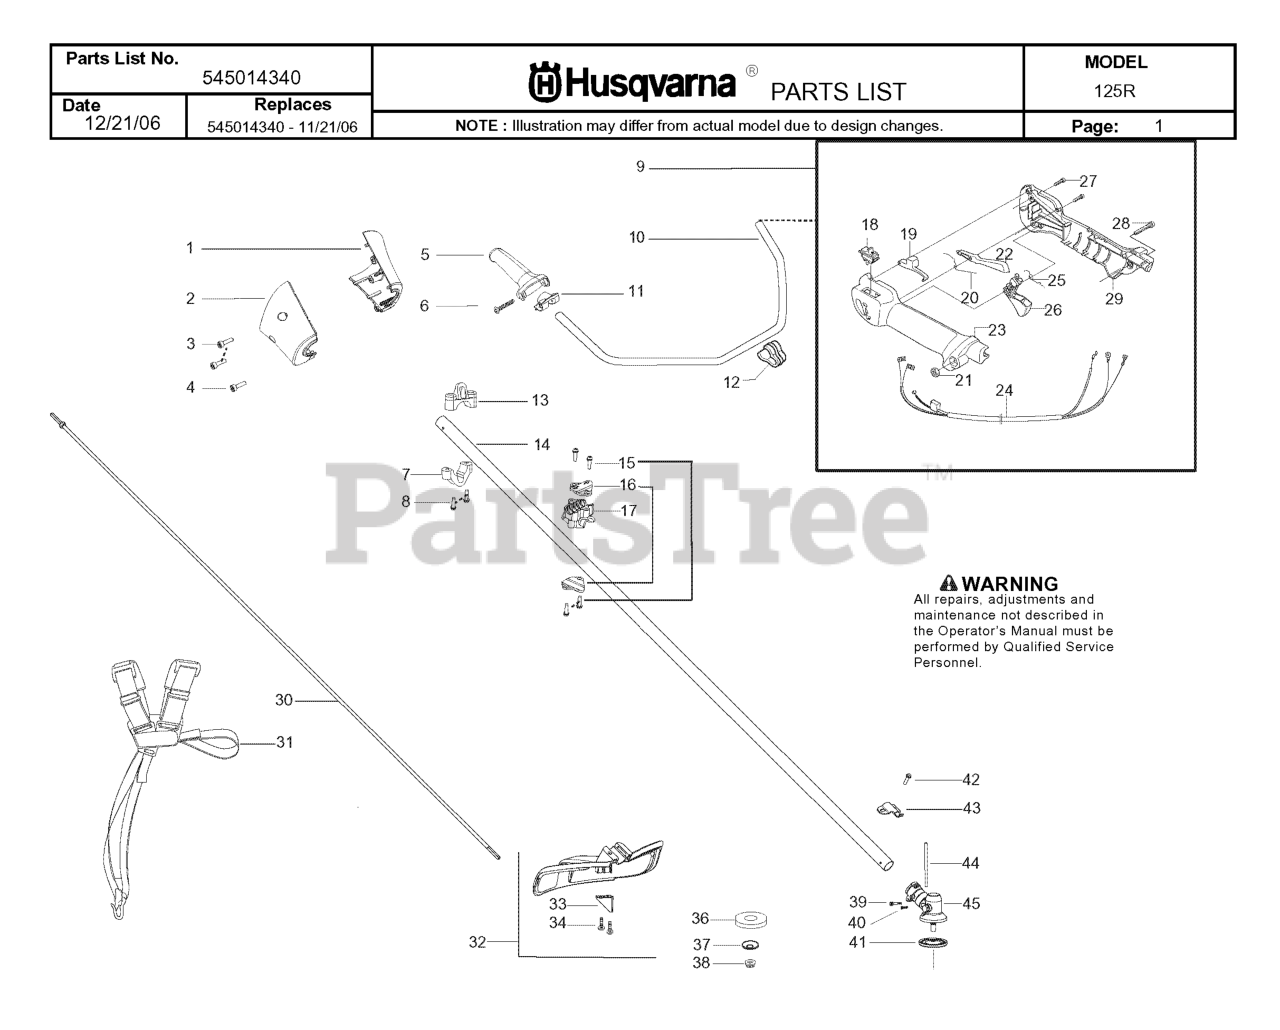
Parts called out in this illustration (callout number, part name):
1	NOSE CONE BH LEFT
2	NOSE CONE BH RIGHT
4	SCREW M4 X 1.75 PT 16MM
7	CLAMP HARNESS LOWER
9	ASSY THROTTLE HOUSING
13	CLAMP HARNESS UPPER
14	DRIVE SHAFT ASSY
16	CLAMP BRACKET
18	STOP BUTTON
19	LOCKOUT STARTER THROTTLE
22	THROTTLE LOCK
26	THROTTLE TRIGGER
28	SCREW
31	HARNESS DUO
32	KIT COBI SHIELD
33	Limiter - Line
36	SUPPORTING CUP
37	SUPPORT FLANGE
38	GEARHEAD NUT - BRUSHCUTTER
39	SCREW - CARB. ADAPTOR
41	DRIVE DISC
42	SCREW 1/4-20 X 7/8 (TAP
43	BRACKET SHIELD STRAIGHT SHAFT
44	LOCKING PIN
45	ASSY GEARBOX
